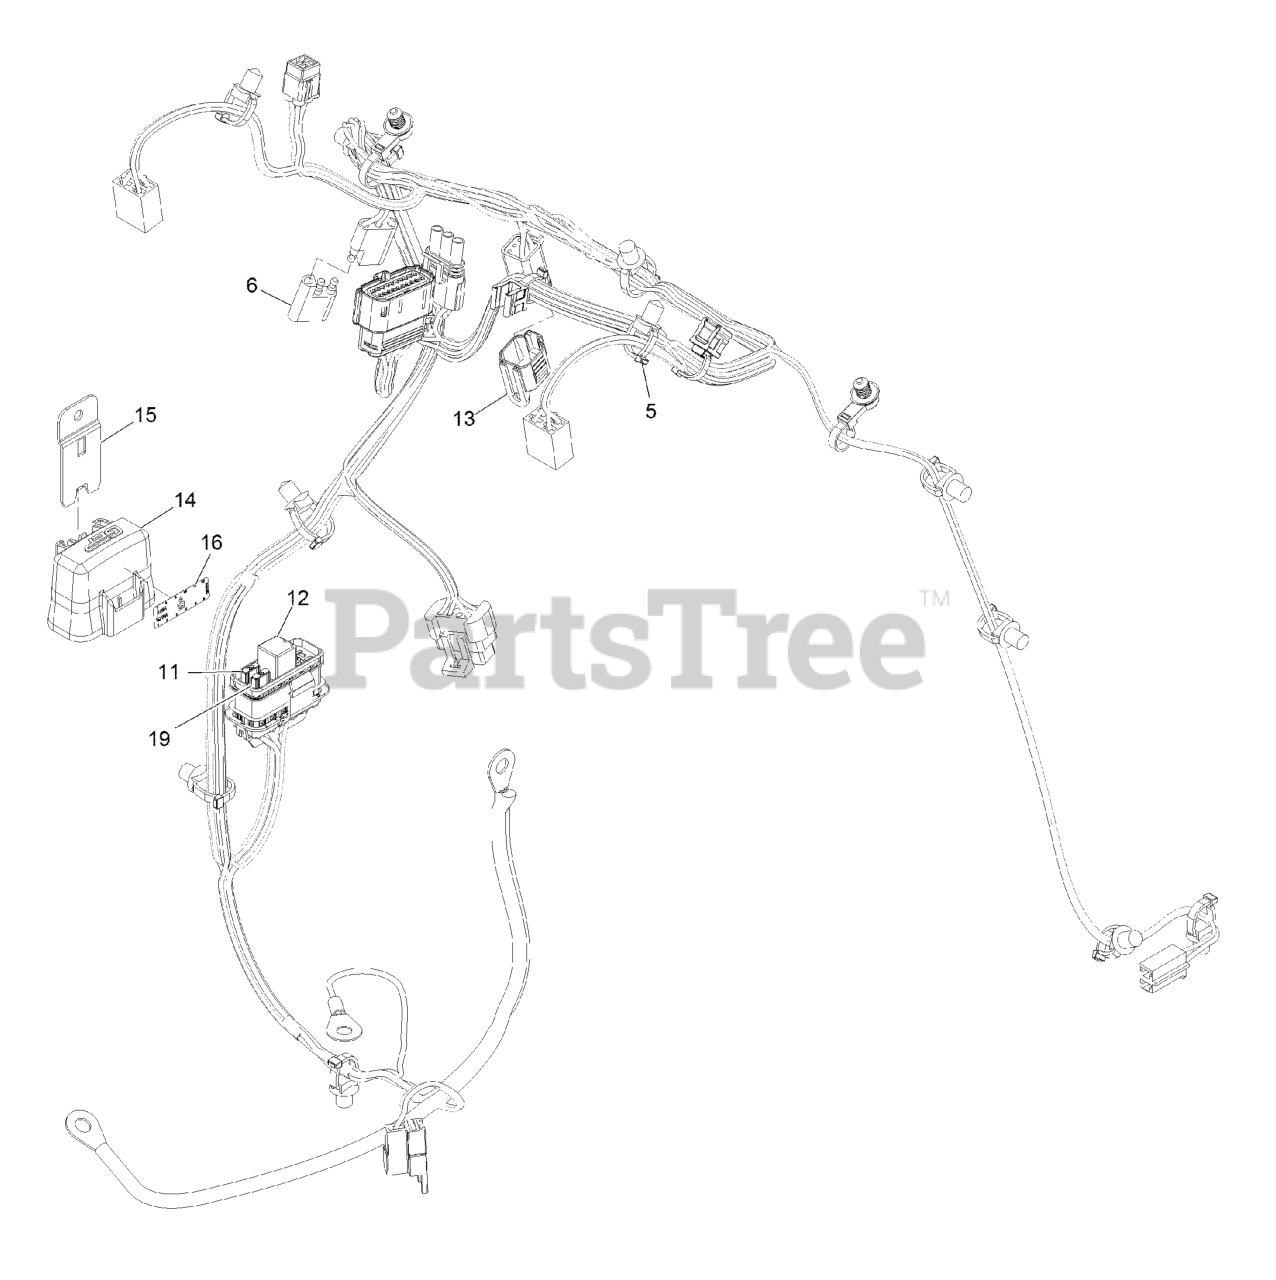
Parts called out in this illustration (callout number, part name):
5	CLIP-TIE
6	Cap-Plug
11	FUSE-MINI BLADE, 20 AMP
12	RELAY-MICRO
13	CAP-PLUG, 6 WAY
14	COVER-BLOCK, FUSE
15	CLIP-MOUNTING
16	DECAL-FUSE
19	FUSE-MINI BLADE, 15 AMP
